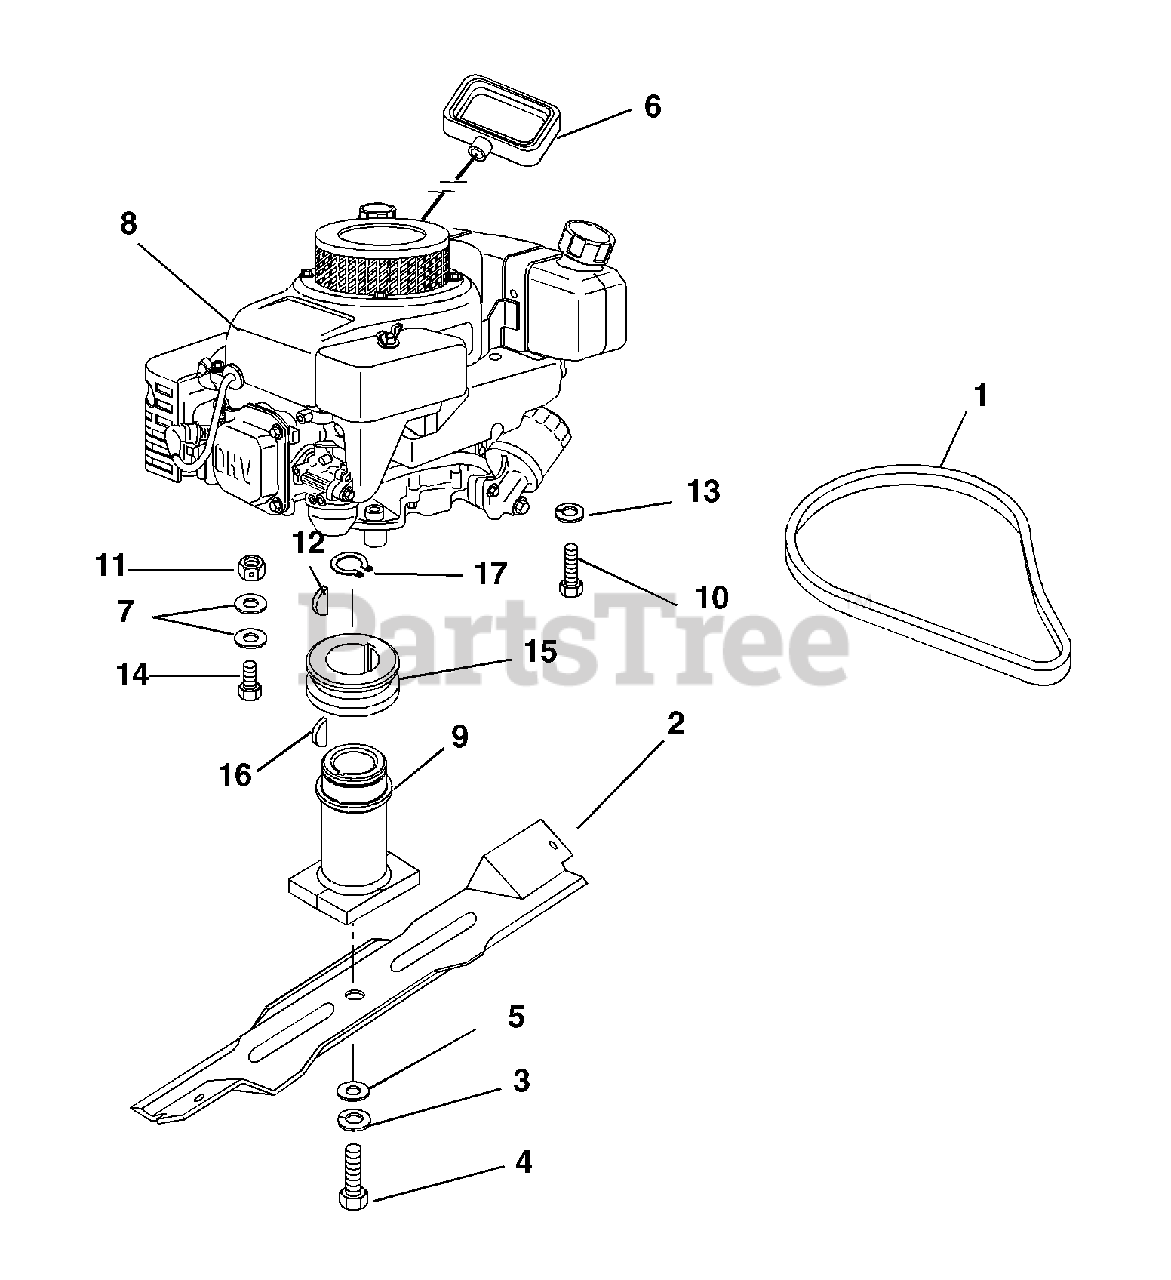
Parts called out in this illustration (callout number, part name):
1	V-BELT, 3L-RAW EDGE
2	BLADE, 21" MOWER TUNGSTEN
3	@WSHR-LK .38X.094 REG YWZC
4	BLT-HEX .38-24 X 2.00 GR8 YWZC
5	WSHR-FL-STL .390X1.5X.125 YWZC
6	HANDLE, RECOIL START
7	@WSHR-FL-STL.312X.734X.065 YWZ
8	ENGINE ROBIN 6HP. PR LUBE.
9	ADAPTER-BLADE,COM
10	@BLT-HEX .31-18X.75 GR5 YWZC
11	@NUT-LK-CTR .31-18 YWZC
12	KEY-WDRF .156X.625X.25 SAE 6
13	WSHR-LK .312X.097 HVY YWZC
14	@BLT-HEX .31-18X1.25 GR5 YWZC
15	SHEAVE-2.94X1.378
16	KEY-WDRF .13X.38 HRD
17	RG-RTNG-EXT 1.375X.050
